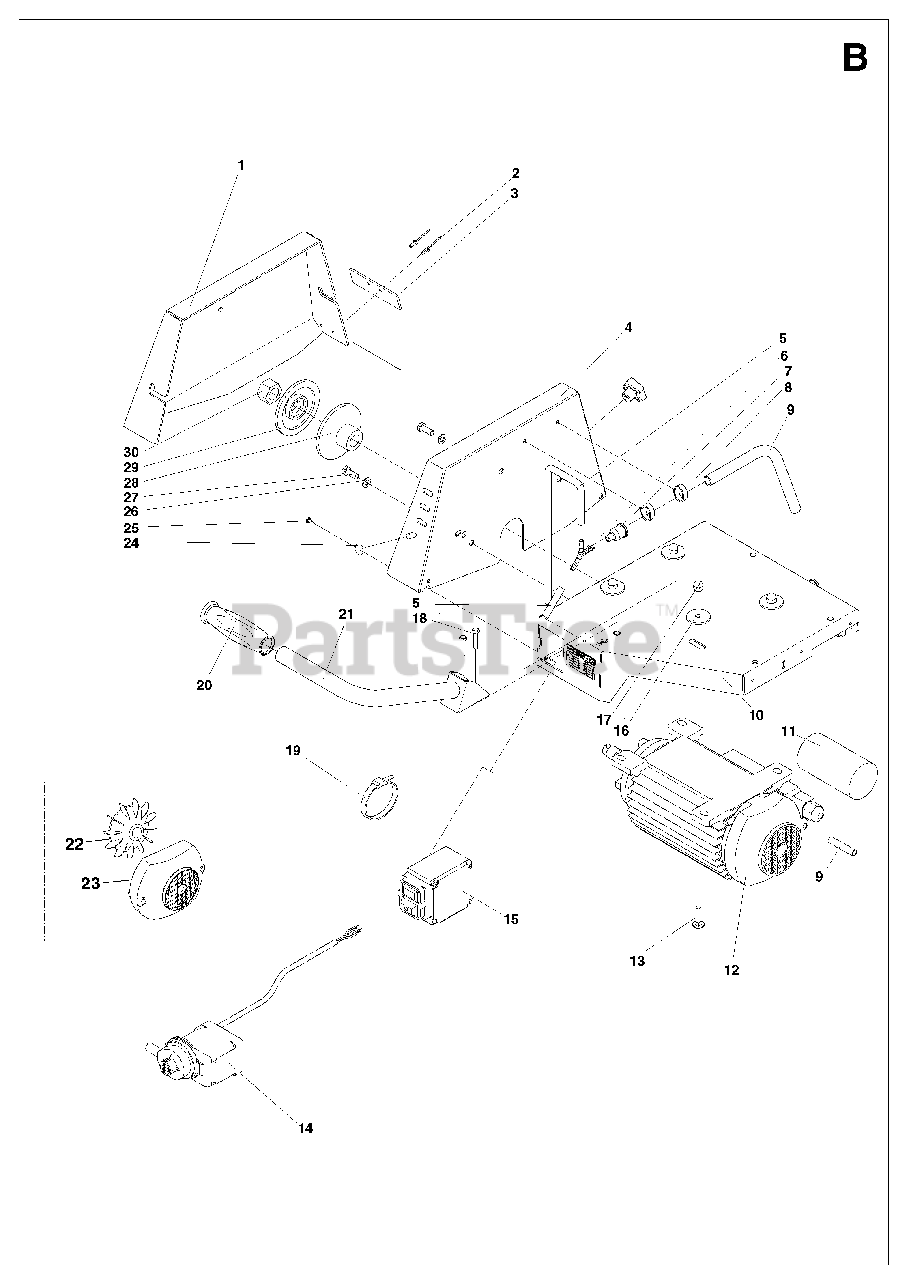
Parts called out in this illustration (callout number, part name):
2	RIVET
6	RACCORD PP CANNELE Y/DIAM INT
8	COLLIER SUPPORT D/19/
26	WASHER
